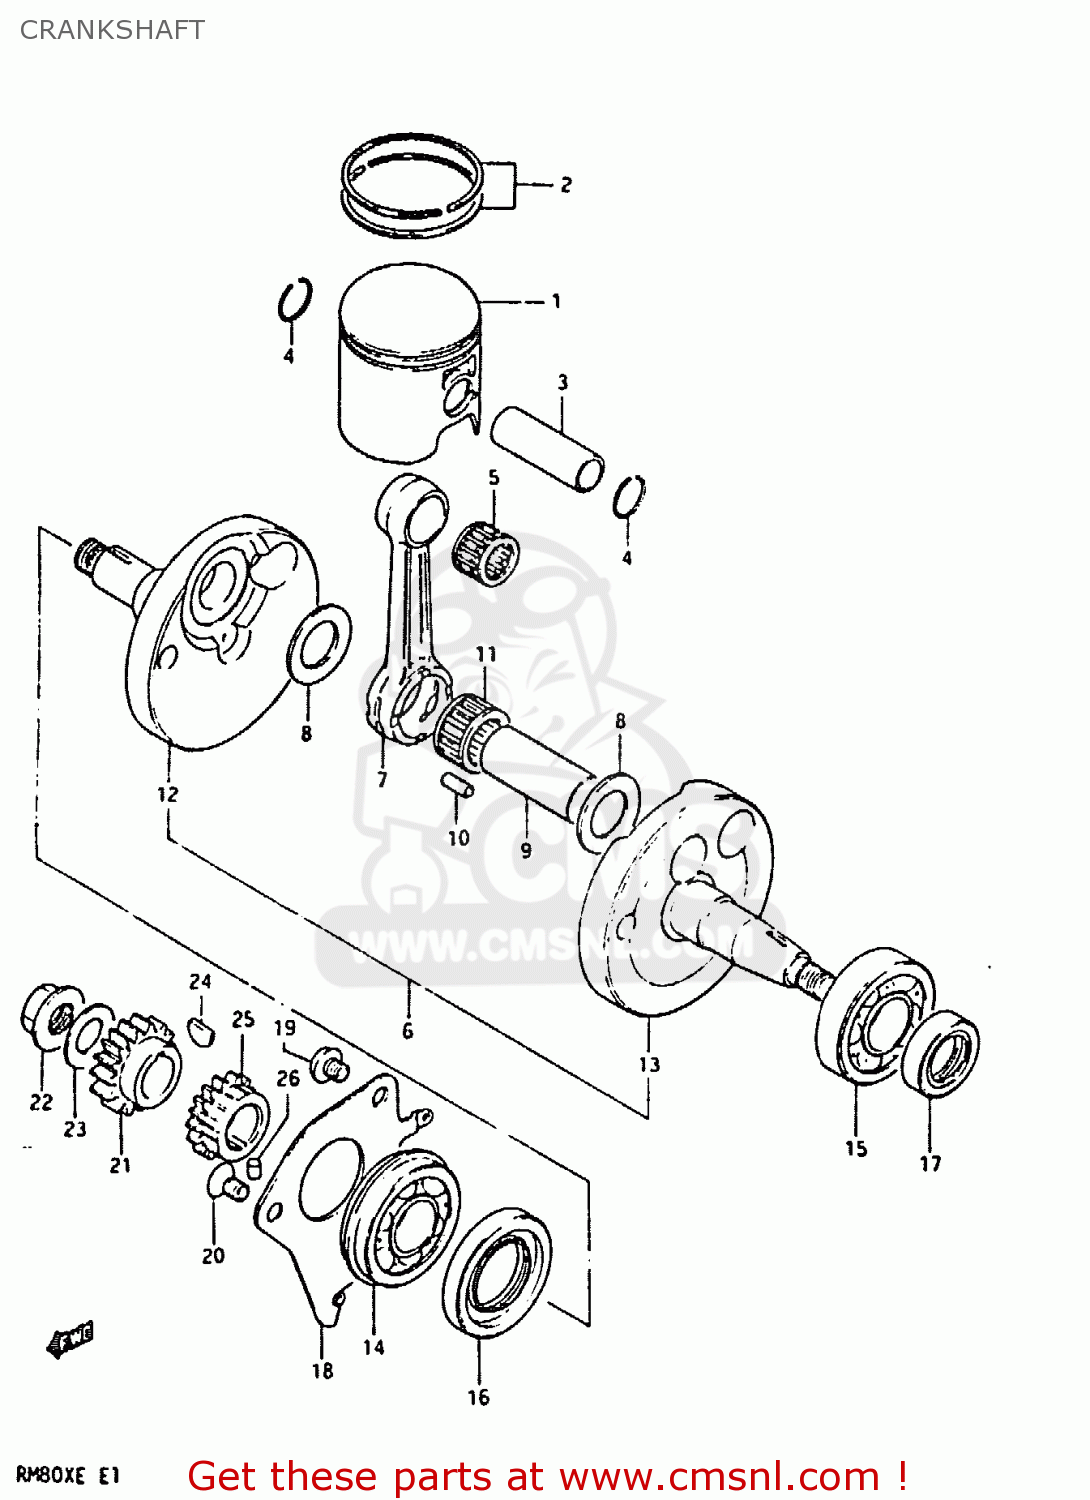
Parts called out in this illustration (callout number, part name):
1	PISTON
2	RING SET,PISTON
3	PIN,PISTON
4	RING,SNAP 14MM
5	BEARING(14X18X16)
6	CRANKSHAFT ASSEMBLY
7	CONNECTING ROD
8	WASHER
9	PIN,CRANK
10	ROLLER(3X11)
11	CAGE
12	CRANKSHAFT
13	CRANKSHAFT,LEFT
14	BEARING(20X47X14)
15	BEARING
16	SEAL,OIL(26X47X7.3)
17	SEAL,OIL(18X30X8)
18	PLATE,CRANKSHAFT BEARING
19	SCREW 6X12
20	SCREW
21	GEAR,PRIMARY DRIVE
22	NUT
23	WASHER
24	KEY
25	GEAR,WATER PUMP DRIVE
26	PIN 3X5
